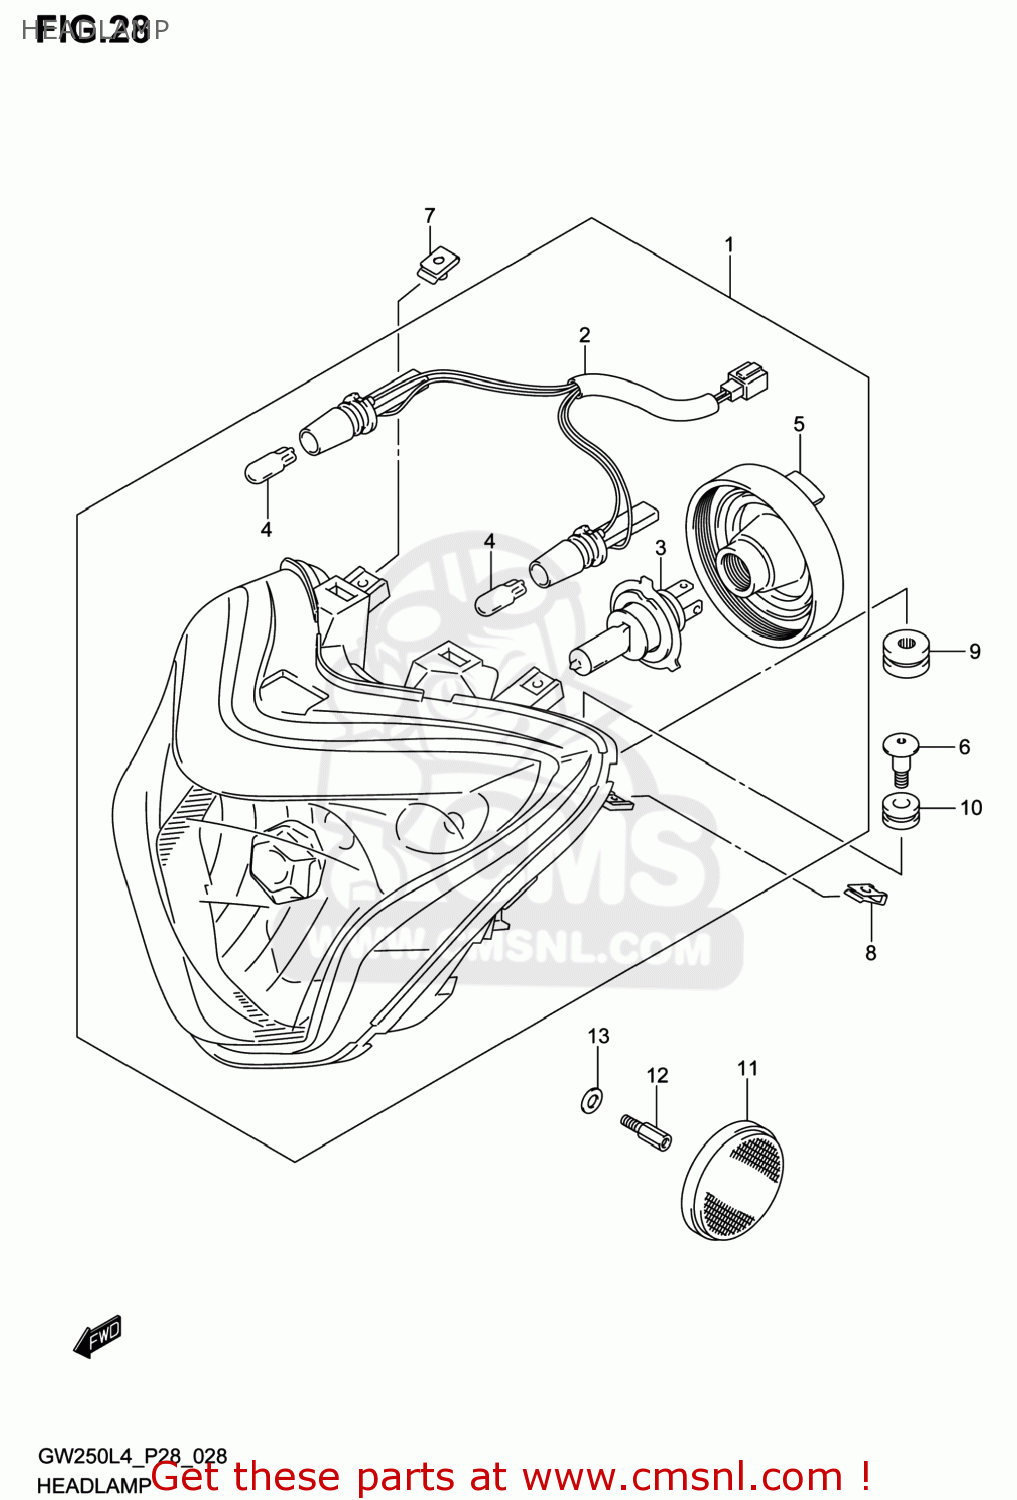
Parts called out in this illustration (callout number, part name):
1	HEADLAMP ASSY
2	CORD ASSY
3	BULB(12V60/55W,H4)
4	BULB(12V5W)
5	CAP
6	SCREW,HEADLAMP
7	NUT,HEADLAMP
8	NUT,HEADLAMP
9	CUSHION,HEADLAMP
10	CUSHION,HEADLAMP
11	REFLEX REFLECTOR ASSY,FR SIDE
12	BOLT(6X18)
13	WASHER
